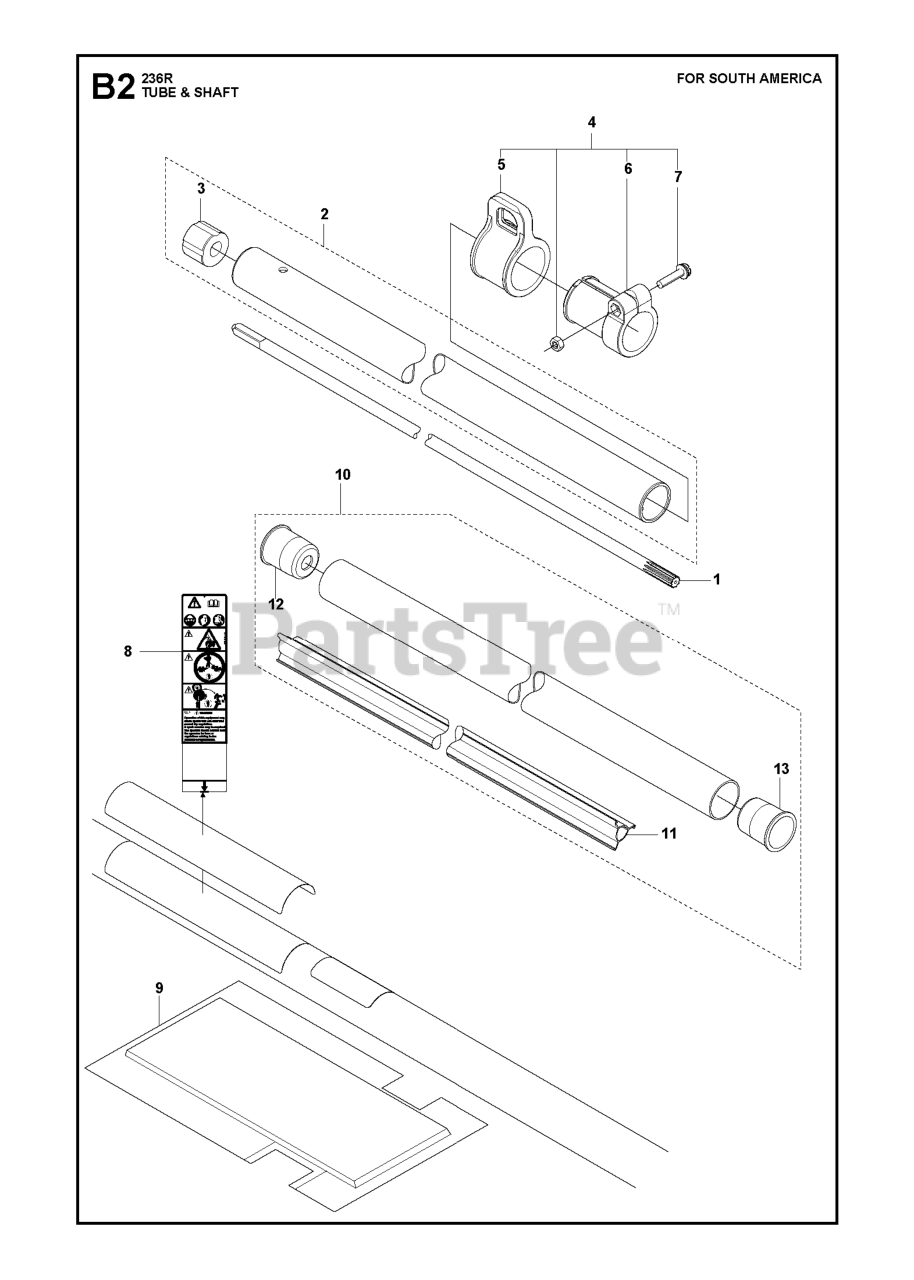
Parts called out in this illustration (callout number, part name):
1	DRIVE SHAFT
2	PIPE COMP.
8	LABEL WARNING TRIMMERS AND BRU
9	PROTECTOR (RPLS 405017110)
12	PLUG
13	PLUG
